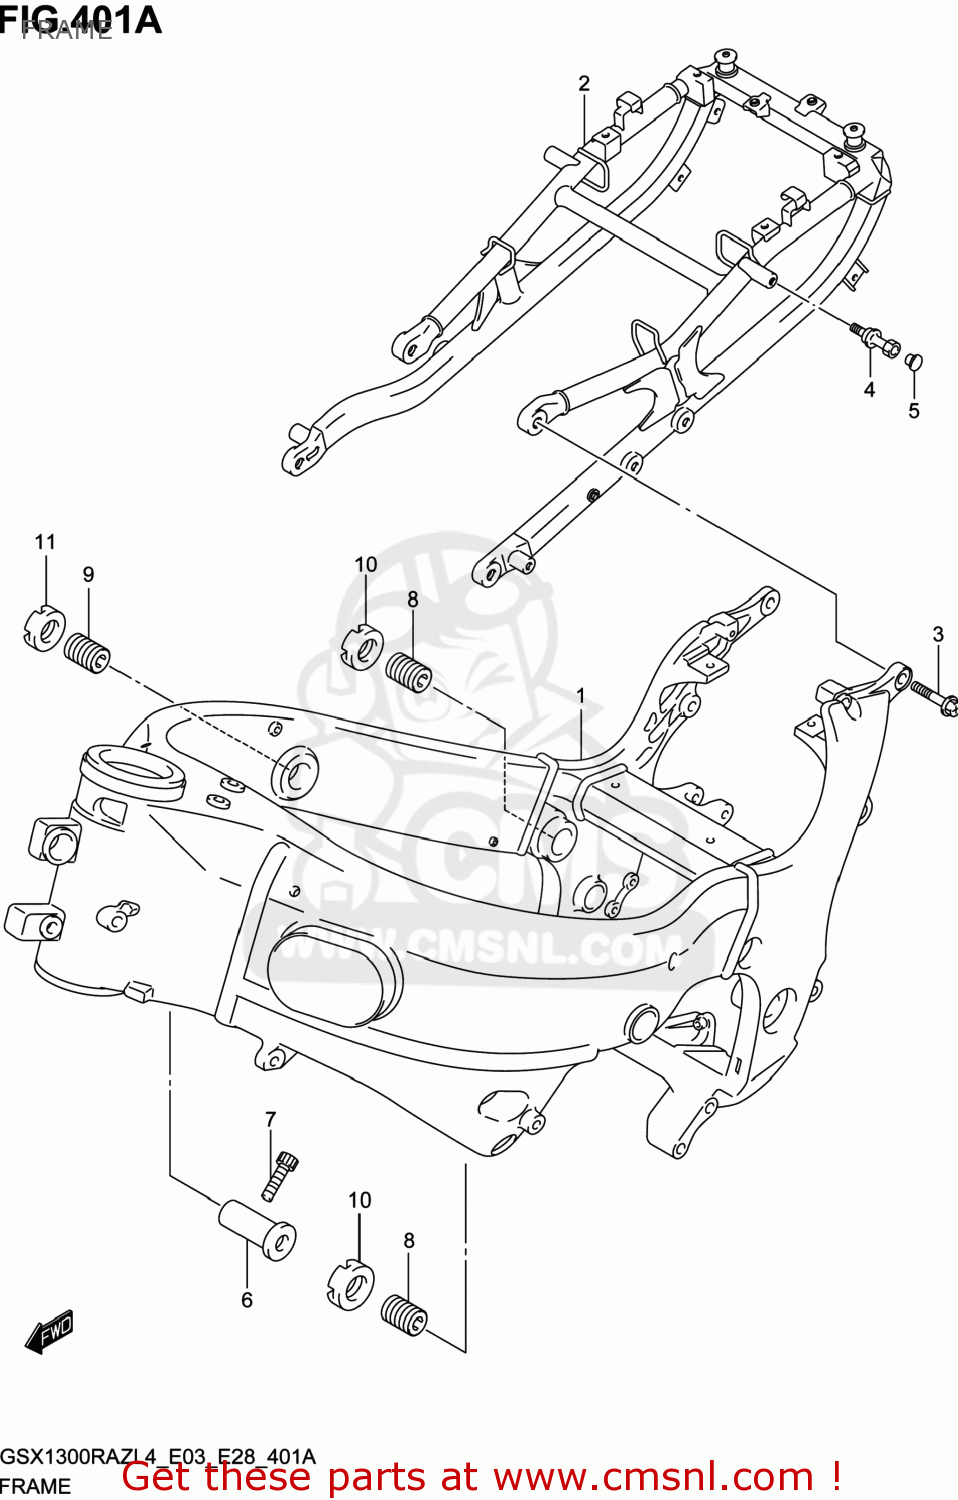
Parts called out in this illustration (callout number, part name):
1	FRAME(BLACK)
2	RAIL,SEAT
3	BOLT(10X30)
4	HOOK,SEAT RAIL
5	CAP(OD:10)
6	SPACER,ENGINE MTG
7	BOLT(8X30)
8	BOLT,CRANK CASE ADJUST
9	BOLT,CRANK CASE ADJUST
10	NUT,CRANK CASE ADJUST
11	NUT,CRANK CASE ADJUST BOLT
